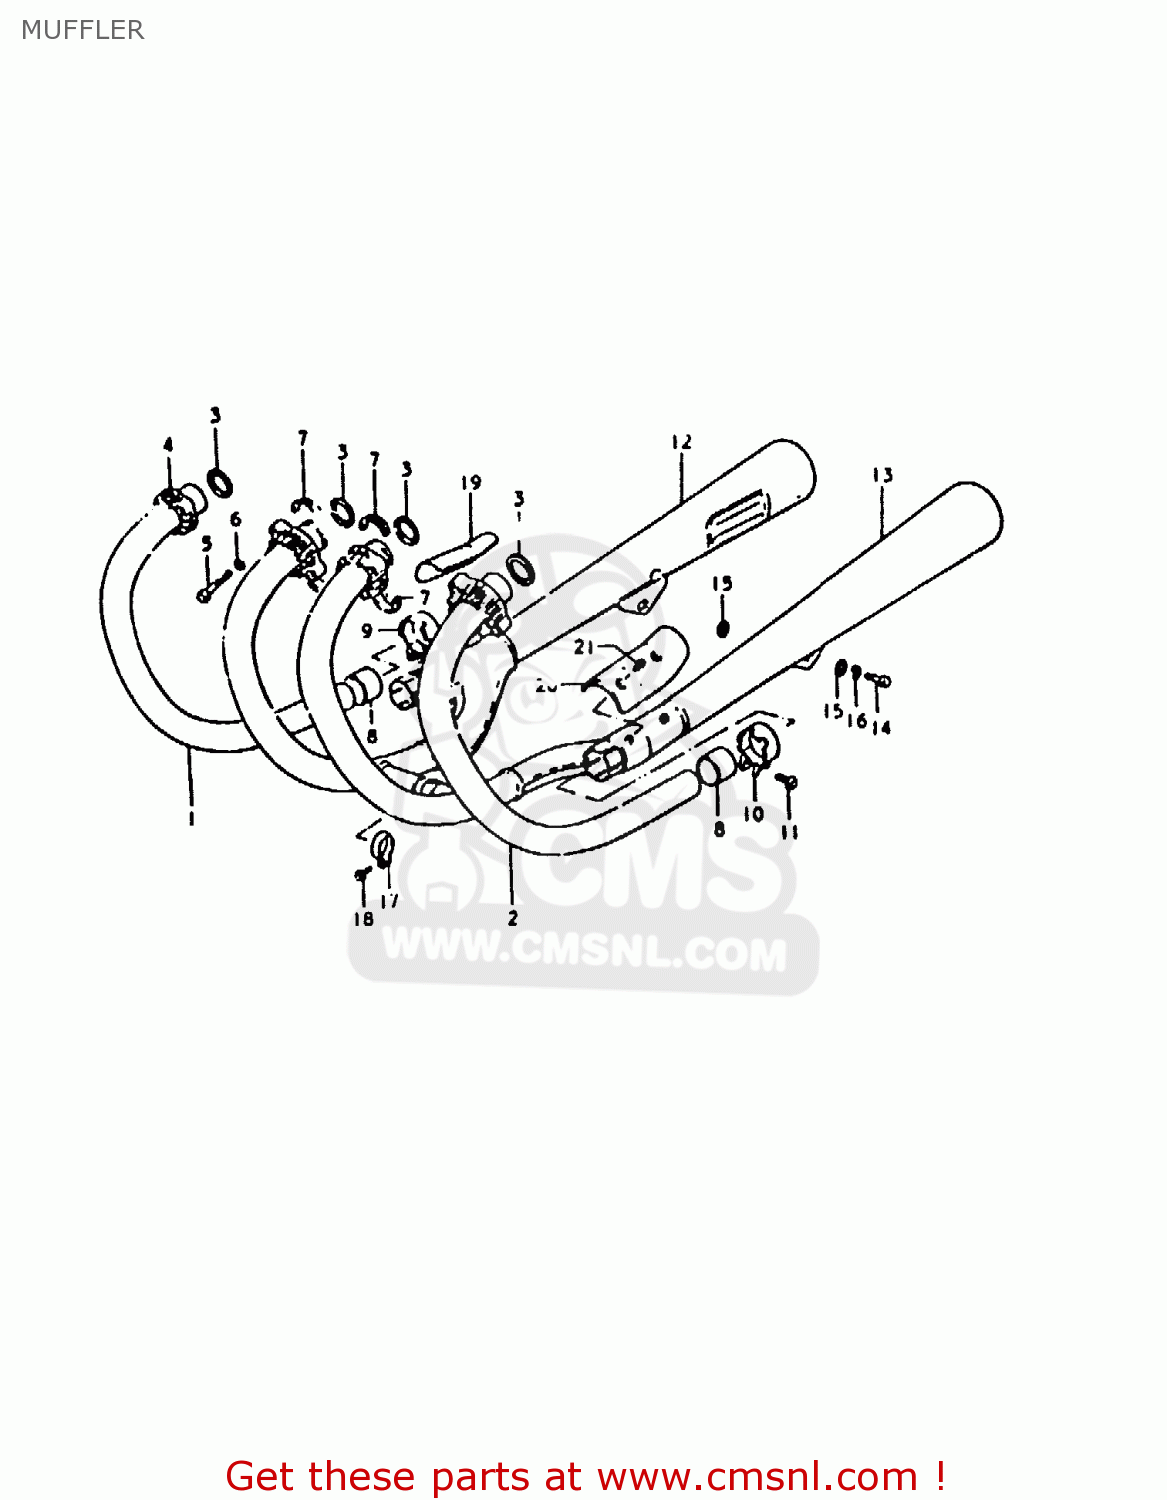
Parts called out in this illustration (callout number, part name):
1	PIPE,EXHAUST,R
2	PIPE,EXHAUST,L
3	GASKET,EXHAUST PIPE (NAS)
4	CLAMP,EXHAUST PIPE
5	BOLT
6	LOCK WASHER
7	PLATE,EXHAUST P
8	CONNECTOR,MUFFLER
9	CLAMP,MUFFLER CONNECTOR,R
10	CLAMP,MUFFLER CONNECTOR,L
11	BOLT
12	BODY,MUFFLER
13	BODY,MUFFLER
14	BOLT 10X30
15	WASHER
16	LOCK WASHER
17	CLAMP
18	BOLT
19	COVER,MUFFLER
20	COVER,MUFFLER,LEFT
21	SCREW
